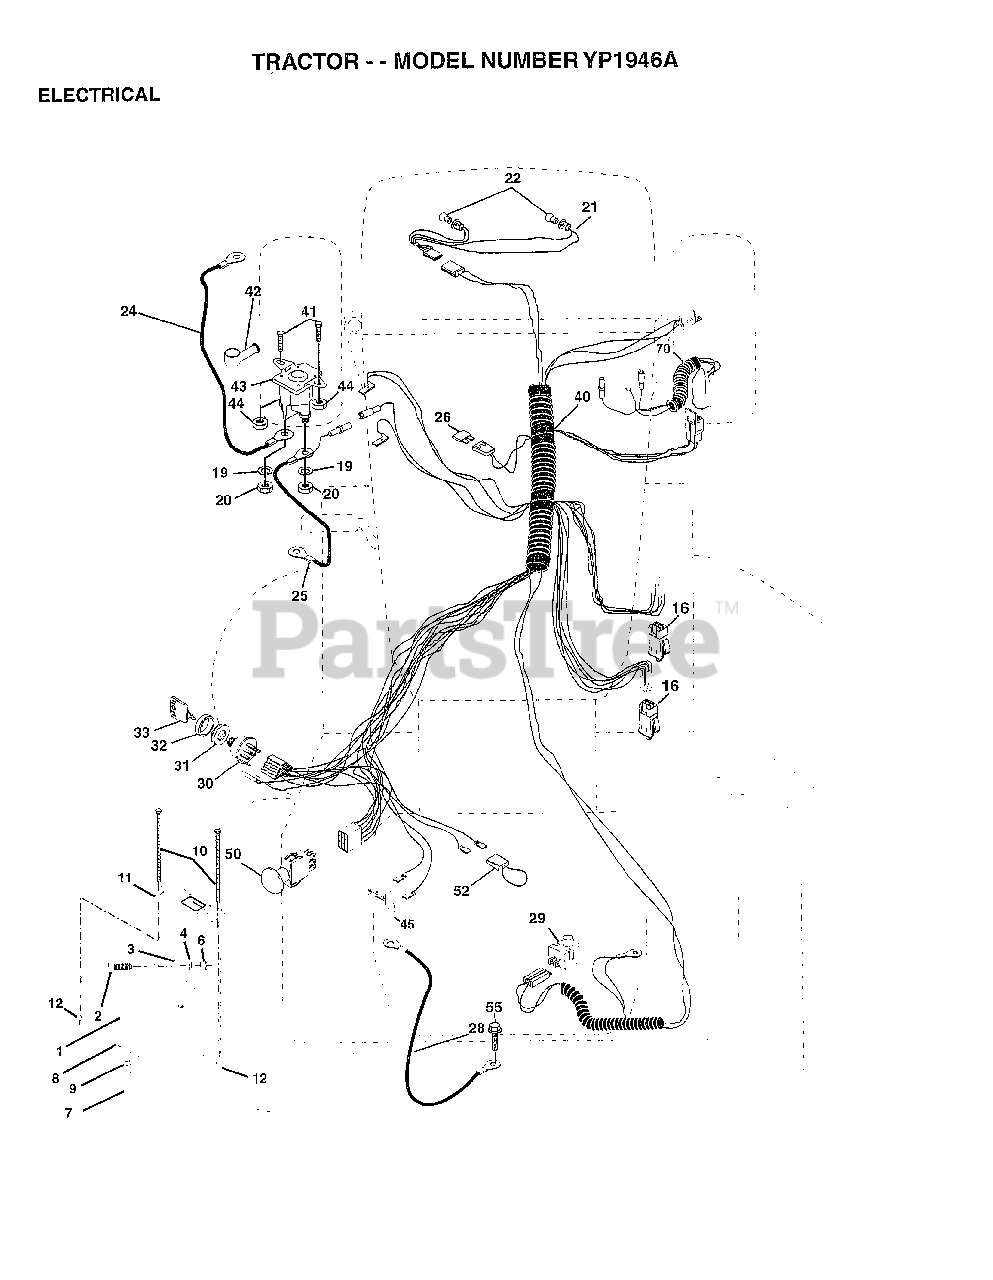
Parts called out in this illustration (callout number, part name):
3	WASHER
4	LOCKWASHER
7	"DRAIN TU T, BATT"
8	"TRAY T, BATTERY"
9	HOSE CLAMP T
11	HOLDDOWN BATTERY
16	SWITCH INTERLOCK
20	NUT
21	"HARNESS,LIGHT SOC"
22	HEADLAMP BULB
24	"CABLE T, BATTERY"
25	CABLE.6GA.22W/16W
26	FUSE HYT
28	CABLE.GRND.6GA.21
29	SWITCH SEAT
30	SWITCH IGN 4POS
31	NUT IGNITION
32	COVER KEY SWITCH
33	KEY
40	HARNESS IGNITION
41	BOLT HXHD FIN
44	NUT HXKEP 1/4X20
45	AMMETER
50	PTO SWITCH.BLK
52	PROTECTION LOOP
55	SCREW LT
70	HARNESS ENG B&S
